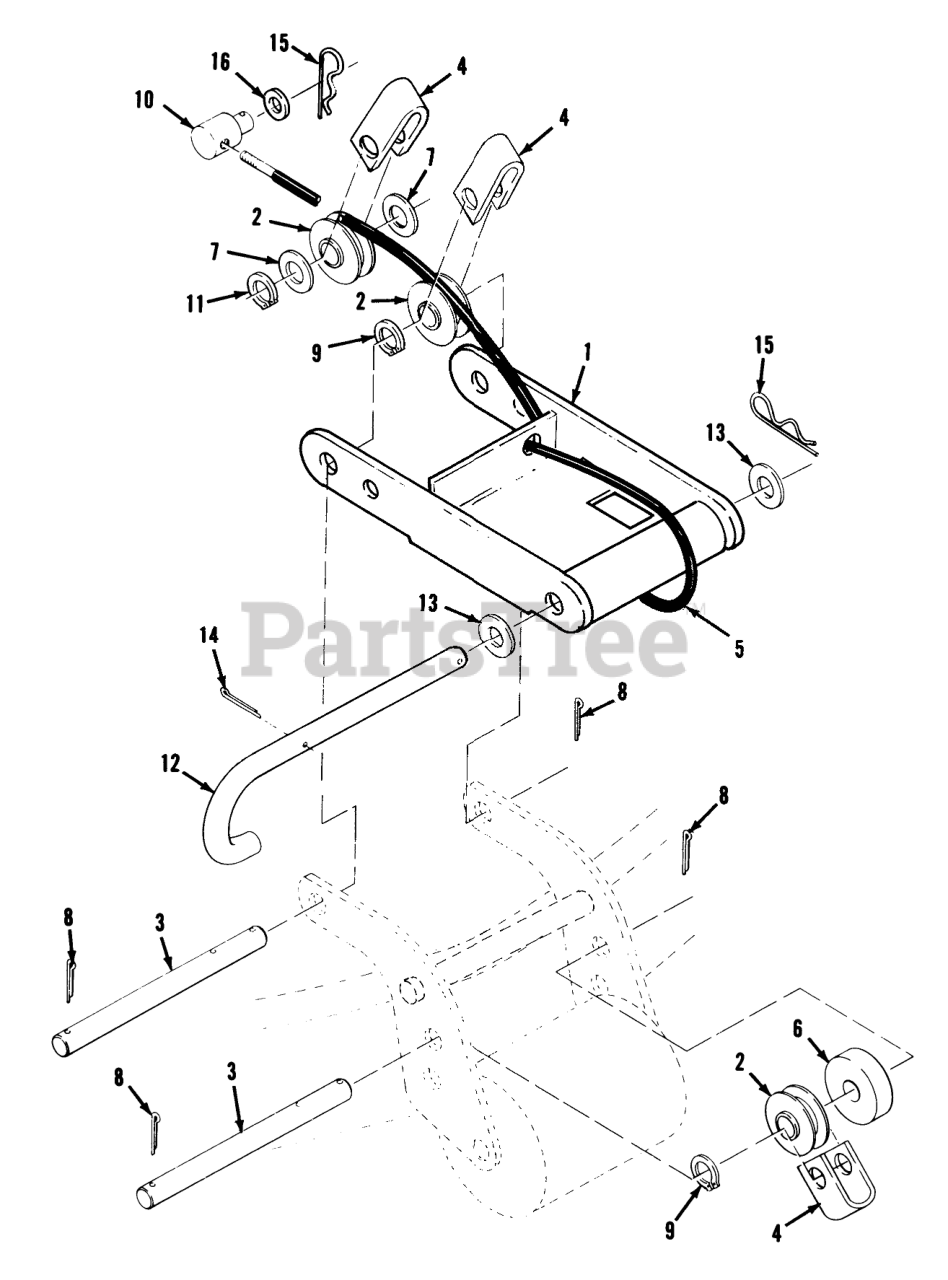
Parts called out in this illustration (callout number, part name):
1	ASSY-FRT MTG BRKT R
1	ASSY 42" MOWER RE R
2	ROLLER-CABLE
3	ROD CABLE ROLLER
4	STRAP-CABLE
5	ASSY-CABLE
6	SPACER
7	WASHER-FLAT
8	PIN-COTTER
9	GRIP RING
10	TRUNNION
11	GRIP RING
13	WASHER-FLAT
14	PIN-COTTER
15	Hairpin Cotter
16	WASHER-FLAT
